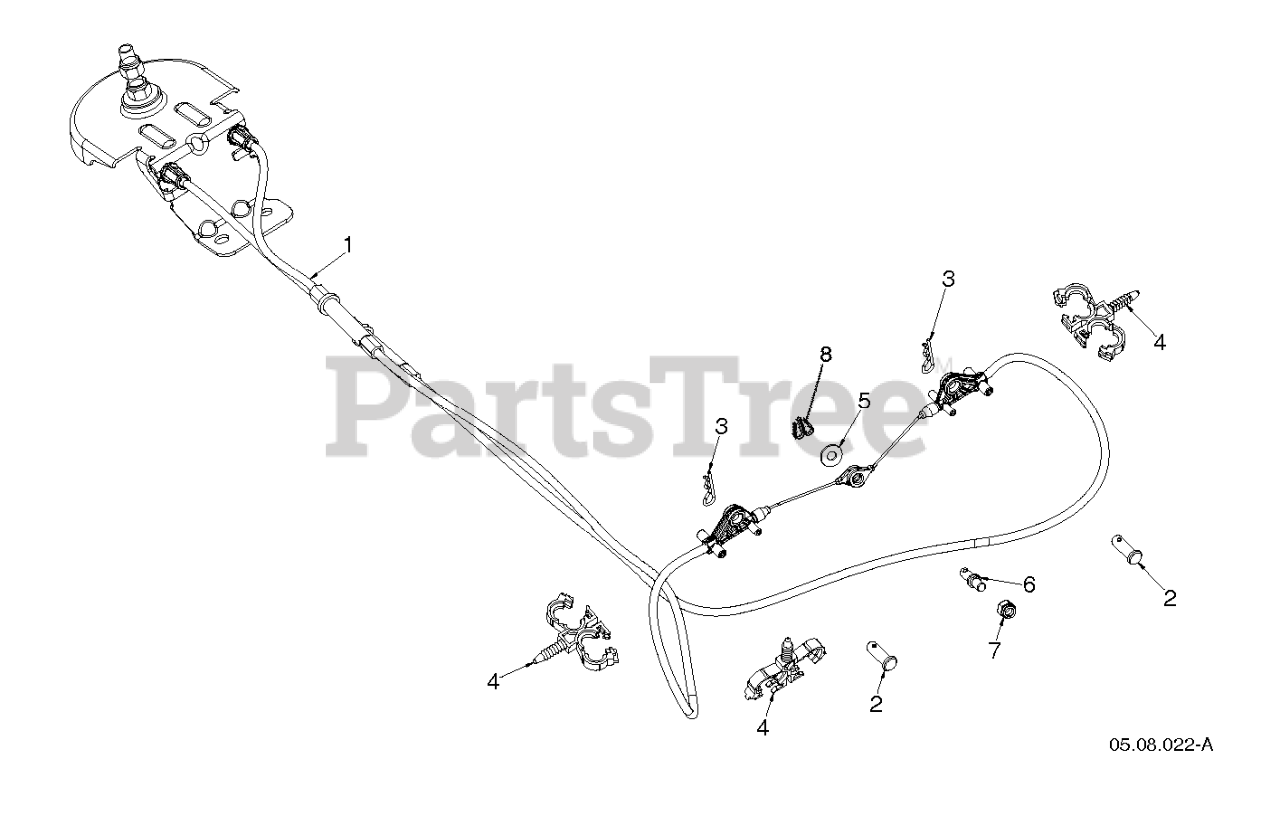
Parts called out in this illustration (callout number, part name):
2	PIN CLEVIS 5/16X.875
3	HAIRPIN.SOFT.ZINC.059X1.125
4	CLIP.CONDUIT.DOUBLE LOOP
5	WASHER FLAT_.250 X .625 X .06
6	Clevis Pins
7	NUT HEXAGON 1/4-20 ST ZPB
